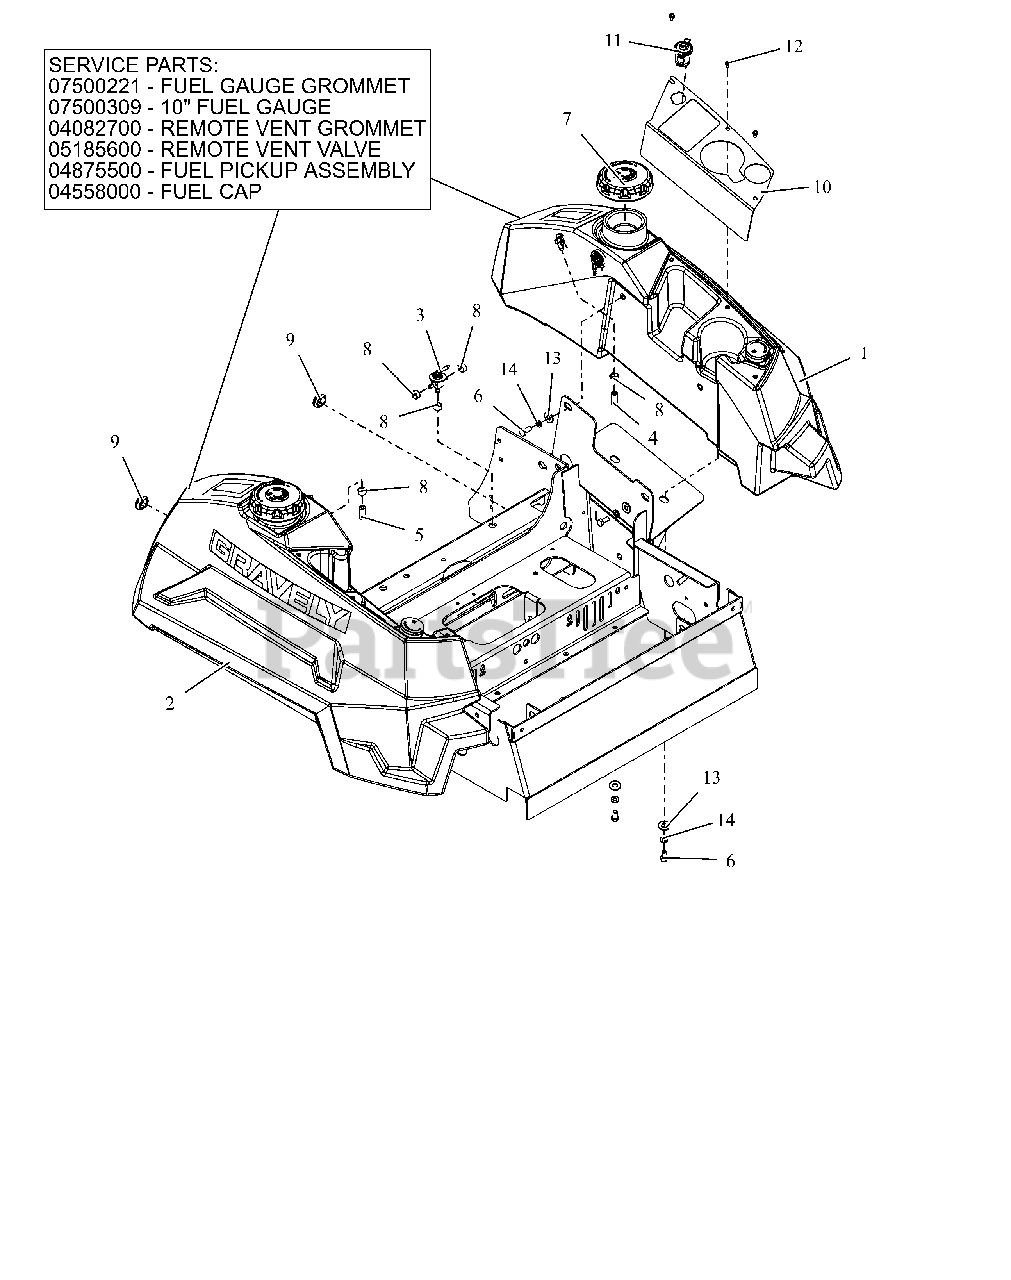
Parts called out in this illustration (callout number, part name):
1	ASM, PT200/400 LH FUEL TANK
2	ASM, PT200/400 RH FUEL TANK
2	GROMMET, FUEL GAUGE
2	GAUGE, REMOTE FUEL SEALED 10"
2	GROMMET, REMOTE VENT NITRILE
2	VALVE, COMBINATION VENT 3/16
2	ASSM,LRG TANK FUEL PICKUP LINE
2	CAP, FUEL VENTIN AUTOLOCK
3	VALVE - FUEL
4	HOSE, .25 LOW-PERM BULK GAS
5	HOSE, .25 LOW-PERM BULK GAS
6	@BLT-HEX .31-18X.75 GR5 YWZC
7	CAP, FUEL NONVENT AUTOLOCK
8	CLAMP, FUEL LINE
9	GROMMET,RUBBER 5/8 ID/1.13 OD
10	CUP HOLDER/POCKET PLATE - RED
11	PORT, 12 VOLT POWER
12	SCR-MCH 10-24X.38 HWHSTAINLESS
13	@WSHR-FL-STL.38X.875X.083 YWZC
14	@WSHR-LK .31X.078 REG YWZC
